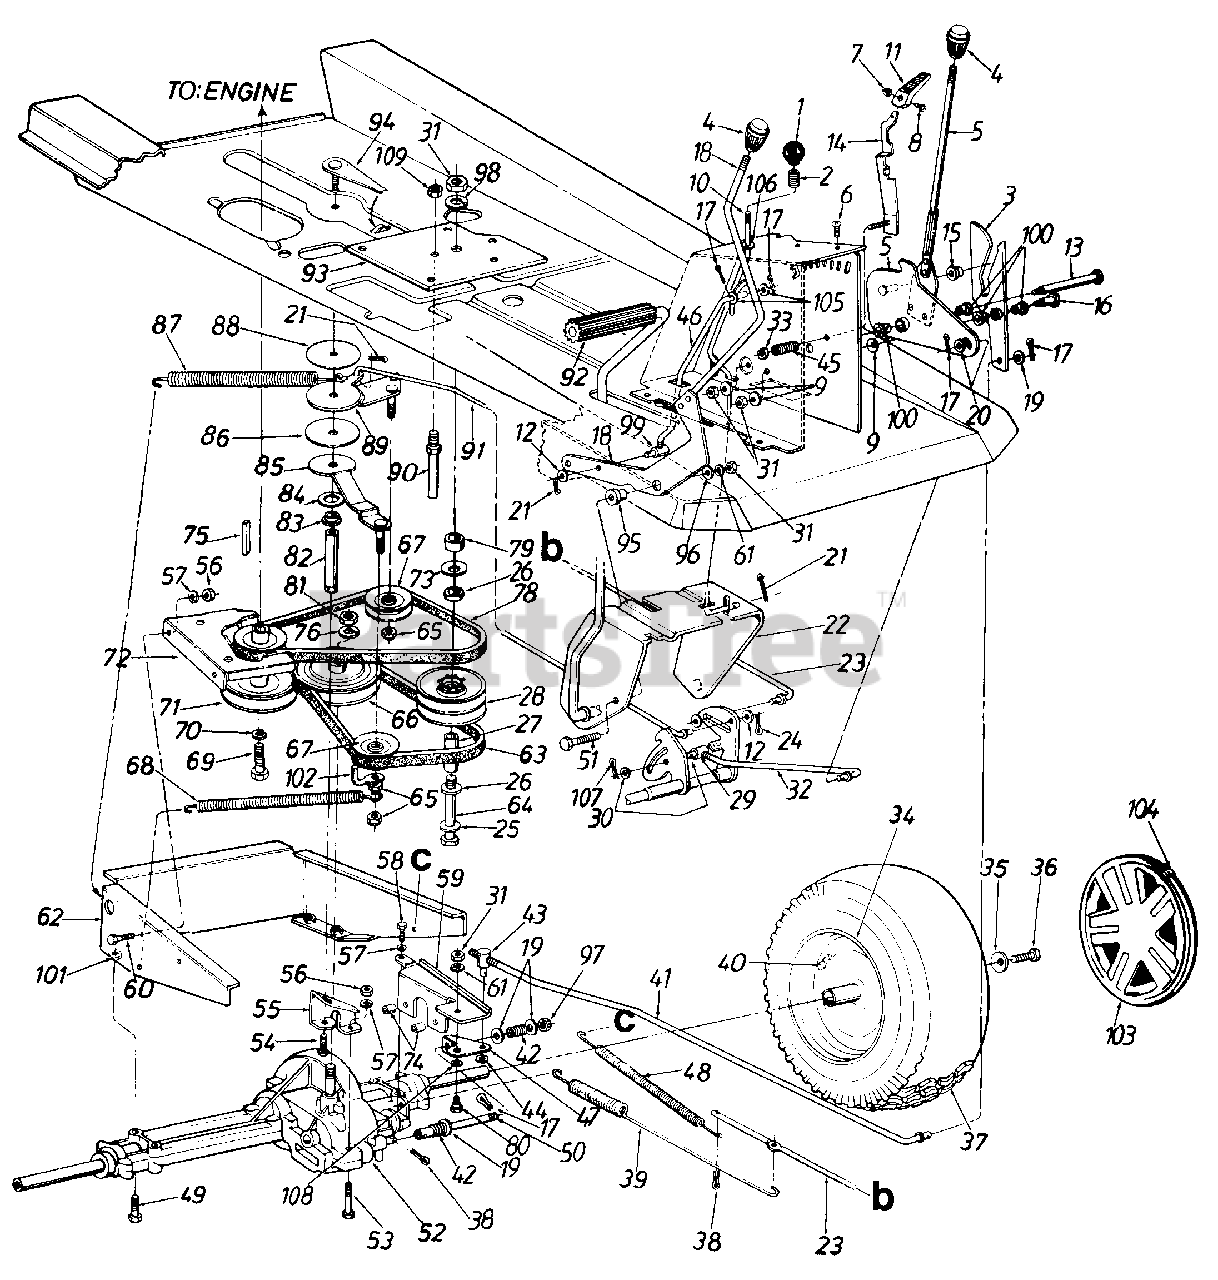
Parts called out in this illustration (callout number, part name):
1	Ball Knob 1/4-20 Thd.
2	Compression Spring
3	Cam Follower Ass'y.
4	Shift Knob
5	Shift Cam w/Handle
6	Pan Hd. Tap Scr. #12 x .5" Lg.
7	Hex Nut #8-32 Thd.
8	Truss Hd. Scr. #8-32 x .38" Lg.
9	Bell-Wash..4" I.D.
10	Parking Brake Rod
11	Knob
12	Fl-Wash. .34" I.D. x .68" O.D.
13	Shld. Bolt 5" Dia. x 3.9" Lg.
14	Speed Control Brkt. Ass'y.
15	Shld. Spacer .38" I.D.
16	Shld. Bolt. .498" Dia. x .71"
17	Cotter Pin 1/8" Dia. x 1" Lg.
20	Fl-Wash. .344" I.D. x .62"
21	Cotter Pin 3/32" Dia. x .75"
22	Clutch Pedal Brkt. Ass'y.
23	Brake Rod
24	Cotter Pin 1/8" Dia. x 1.0"
25	Fl-Wash. .406" I.D. x 1.125"
26	Thrust Brg. .56" I.D.
27	Spacer Sleeve 2.71" Lg.
28	Variable Speed Pulley Ass'y.
29	Ferrule
30	Fl-Wash. .344" I.D. x .88"
31	Hex Nut 3/8-16 Thd.
32	Speed Control Rod
33	Hex Nut 5/16-24 Thd.
35	Bell-Wash. .345" I.D. x .88"
36	Hex L-Bolt 5/16-24 x .75" Lg.
38	Cotter Pin 1/8" Dia. x 1.25"
39	Extension Spring 17" Lg.
40	Air Valve
41	Shift Rod
42	Compression Spring 1.2" Lg.
43	Adjustment Ferrule
44	Fl-Wash. .39" I.D. x 1.0"
45	Compression Spring 1.04" Lg.
46	Reverse Lockout Rod
47	Gear Shift Brkt.
48	Extension Spring 8.25" Lg.
49	Hex Bolt 5/16-18 x 2.5" Lg.
50	Shift Fork Extension
51	Hex Bolt 3/8-16 x 1.25" Lg.
52	Transaxle (See Breakdowns)
53	Hex Bolt 1/4-20 x 1.75" Lg.
54	Hex Bolt 3/8-24 x .75" Lg.
57	L-Wash. 1/4" I.D.
58	Self-Tap Mach. Scr. 1/4-20 x 1 .37" Lg.
59	Gear Shift Support Brkt.
60	Hex Bolt 1/4-20 x 1.0" Lg.
61	L-Wash. 318" I.D.
64	Hex Bolt 3/8-16 x 4.5" Lg.
65	Hex L-Nut 3/8-24 Thd.
66	"V"-Pulley
67	"V"-Belt Idler
68	Ext. Spring 6.37" Lg.
69	Hex Bolt 7/16-20 x 1.0" Lg.
70	L-Wash. 7/16" I.D.*
71	Engine Pulley (800)
72	Upper Belt Guard
73	Bell-Wash. .40" I.D. x 1.12" O.D.
74	Spacer .256" I.D. x .5" O.D.
75	Sq. Key 1/4" x 2.0" Lg.
76	L-Wash. 1/2" I.D.
78	"V"-Belt
79	Spacer .38" I.D. x 1.0" O.D.
80	Shld. Bolt .5" Dia. x .170" Lg.
81	Hex Nut '/2-20 Thd.
82	Torque Rod
83	Flange Bearing .378" I.D.
84	Fl-Wash. .64" I.D. x 1.24" O.D.
85	Idler Bracket Ass'y.
86	Thrust Washer .635" I.D.
87	Extension Spring 7.58" Lg.
88	Thrust Wash. .385" I.D.
89	Idler Bracket Ass'y. For Clutch
90	Belt Guard Pin 3/8-16 x 2.75" Lg.
91	Clutch Rod
92	Foot Pad
96	Fl-Wash. .406" I.D. x 1.25" O.D.
97	Hex Cent. L-Nut 3/8-16 Thd.
98	L-Wash. 3/8" I.D. (Heavy Duty)
100	Flanged Nyliner Brg.
101	Hex Sems Nut 5/16-18 Thd.
102	Belt Guard
104	Spring Clip
105	Fl-Wash. .344" I.D. x .875" O.D.
106	Fl-Wash. .281" I.D. x .5" O.D.
107	Intern. Cotter Pin 1-1/8" Lg.
108	Fl-Wash. .510" I.D. x .75" O.D.
109	Hex Top L-Jam Nut 3/8-16 Thd.
